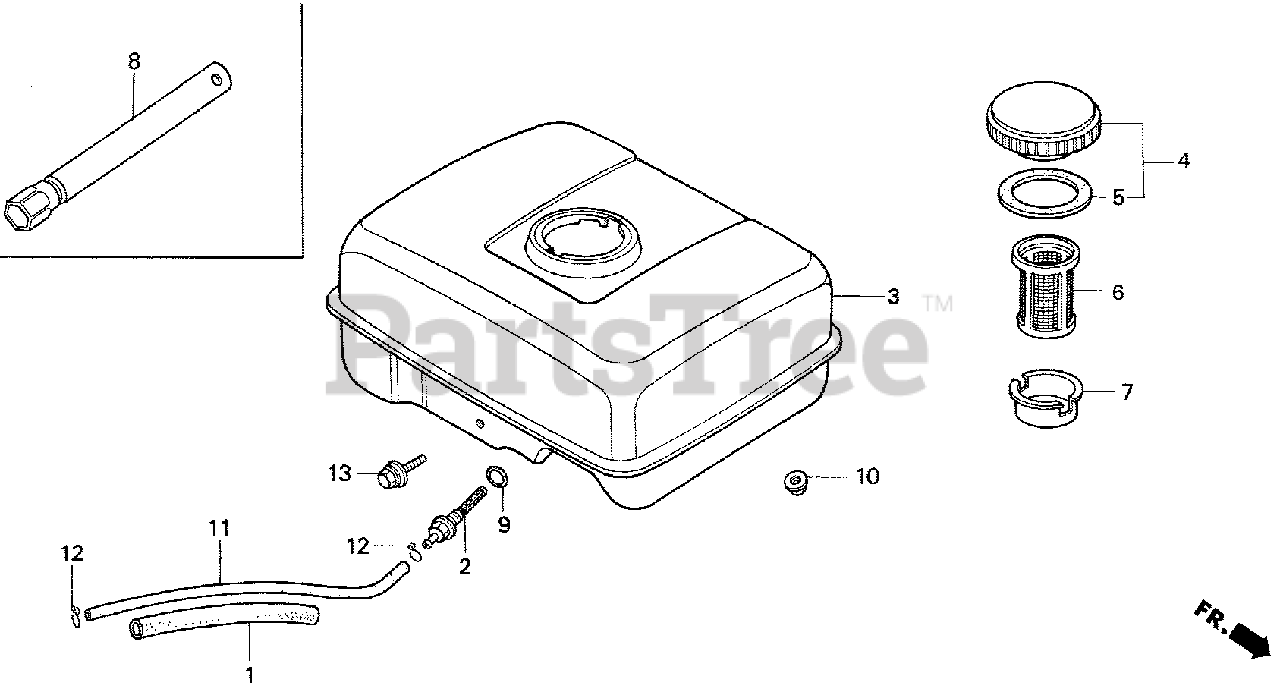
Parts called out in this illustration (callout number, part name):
1	RUBBER, SUPPORTER (107MM)
2	JOINT, FUEL TANK
3	TANK, FUEL *NH31* (MCKINLEY WHITE)
4	CAP, FUEL FILLER
5	GASKET, FUEL FILLER CAP
6	FILTER, FUEL
7	HOLDER, FUEL FILTER
8	WRENCH, SPARK PLUG
9	O-RING (13.5X1.5) (ARAI)
10	NUT, FLANGE (6MM)
11	BULK HOSE, FUEL (4.5X3000) (4.5X140)
12	CLIP, TUBE (B8)
13	BOLT, FLANGE (6X25)
